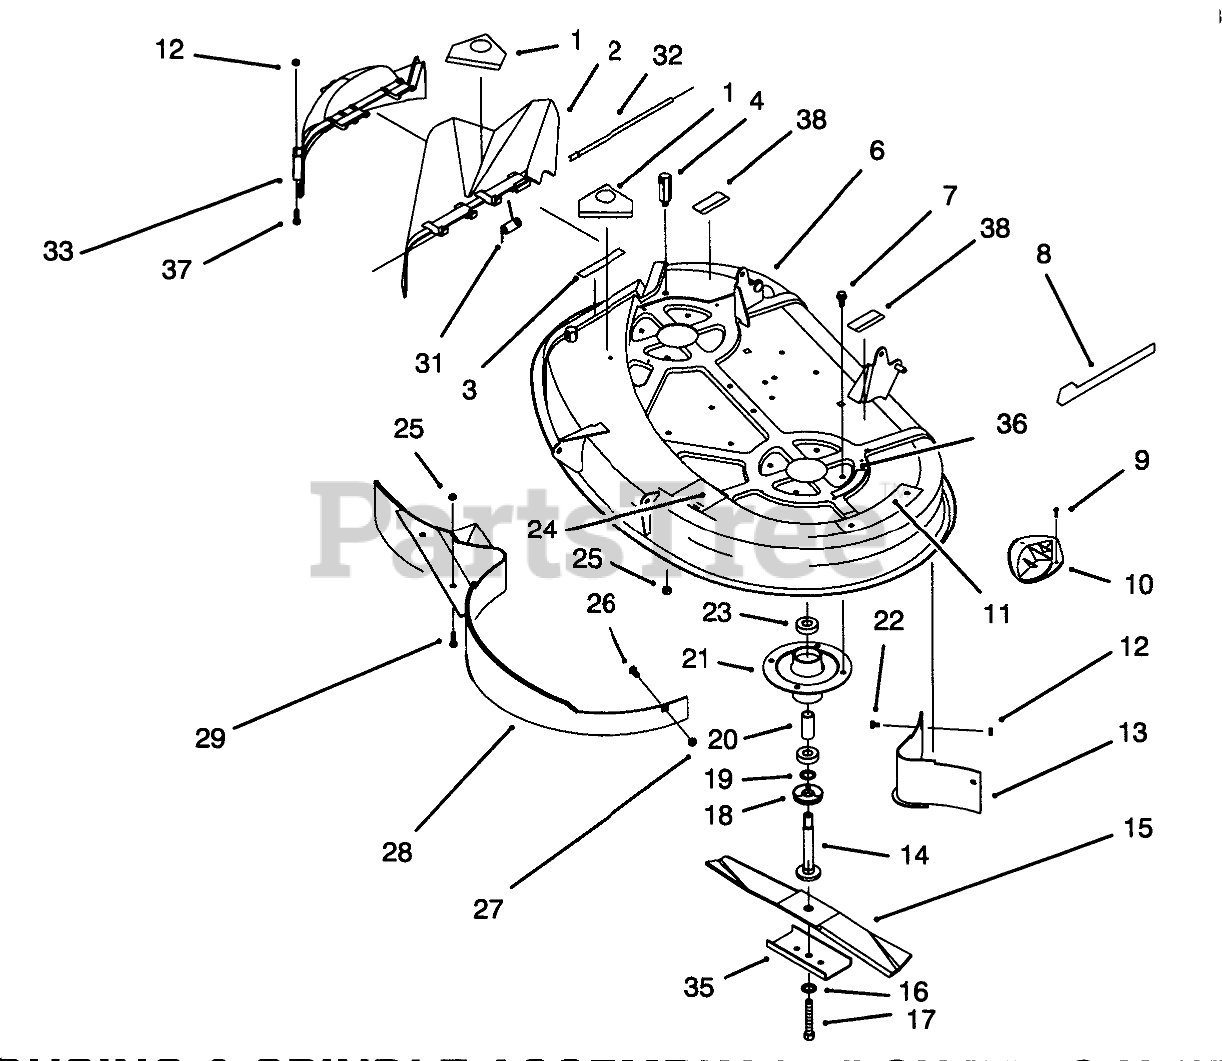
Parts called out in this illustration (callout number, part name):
1	DECAL-DANGER
2	Deflector-Deck
3	DECAL-DANGER, DEFLECTOR
4	REAR PIVOT POST (PLTD)
6	Deck-38"
7	SCREW-TAPTITE
8	DECAL-RECYCLER DECK 38"
9	SCREW-PPH
10	PLATE-KICKER
11	DECAL-DANGER
12	NUT-LOCK, NI
13	Baffle-Rear
14	SHAFT-SPINDLE
15	Blade
16	WASHER-BELLEVILLE
17	SCREW-HH
18	SHIELD-BEARING
19	SPACER
20	SPACER
21	HOUSING-SPINDLE
22	SCREW-HH
23	BEARING-BALL
24	Decal-Routing
25	NUT-LOCK, NI
26	BOLT-CARR
27	NUT-LOCK, NI
28	Baffle-38"
29	SCREW-HH
31	SPRING
32	ROD-HINGE DEFLECTOR
33	COVER-RECYCLER
35	Stiffener
36	DECAL-DANGER, SHIELD
37	SCREW-HH
38	DECAL-WARNING
